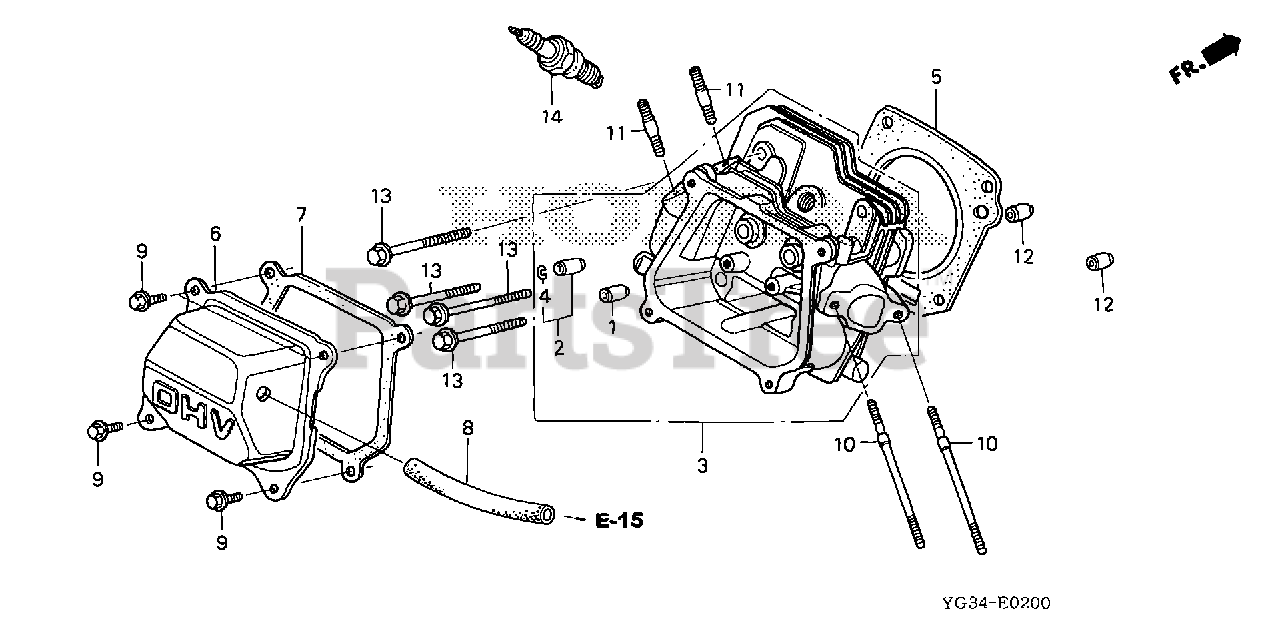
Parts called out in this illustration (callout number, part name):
1	GUIDE, VALVE (OVER SIZE)
2	GUIDE, EX. VALVE (OVER SIZE)
3	CYLINDER HEAD
4	CLIP, VALVE GUIDE
5	GASKET, CYLINDER HEAD (THAI LEAKLESS)
6	COVER, HEAD
7	GASKET, HEAD COVER
8	TUBE, BREATHER
9	BOLT, FLANGE (6X12) (CT200)
10	BOLT, STUD (6X112)
11	BOLT, STUD (8X32)
12	PIN, DOWEL (10X16)
13	BOLT, FLANGE (8X55)
14	SPARK PLUG (BPR6ES) (NGK)
